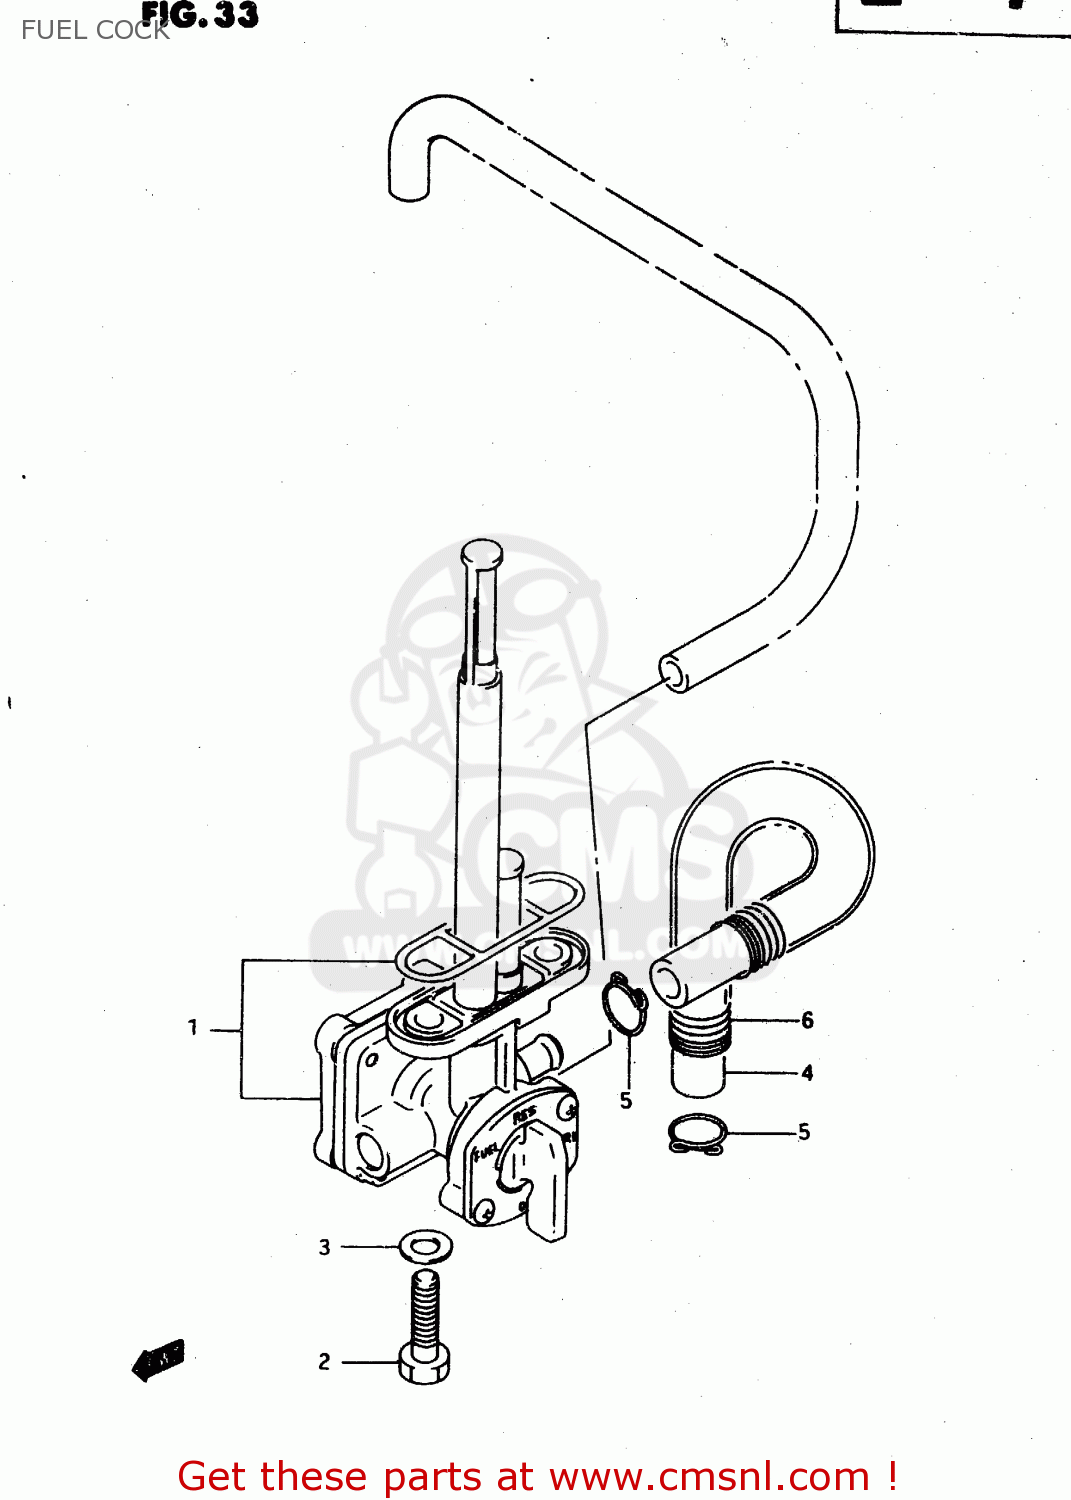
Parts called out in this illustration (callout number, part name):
1	COCK ASSY,FUEL
2	BOLT(6X20)
3	GASKET(6.4X11.5X0.8) (NAS)
4	HOSE(7X11X600)
5	CLIP
6	SPRING
